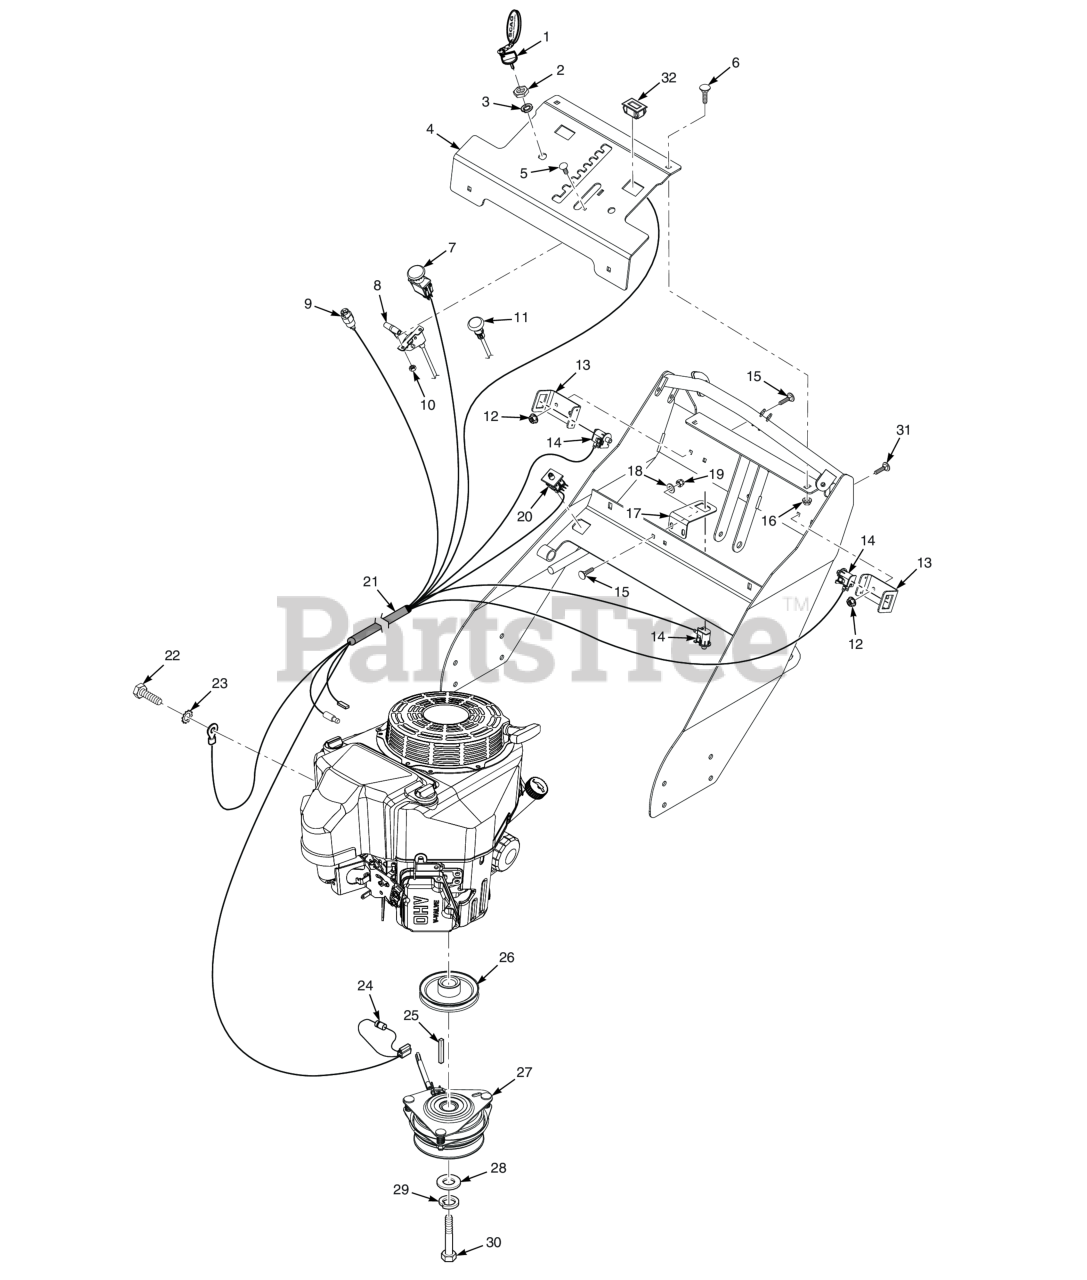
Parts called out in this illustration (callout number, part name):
1	Key, Assembly w/Fob
2	Nut, 5/8-32 Special
3	LOCK WASHER, 5/8" INTERNAL TOOTH
4	Instrument Panel w/Decal
5	Bolt, Carriage #10-24 x 1/2"
6	Bolt, 5/16-18 x .75 RHSN Carriage
7	Switch, PTO - 10 Amp
8	Throttle Cable
9	KEY SWITCH, MANUAL SRT.(INCL. HWD)
10	Nut, Elastic Stop #10-24
11	Choke Control
12	NUT, 1/4-20 SERRATED FLANGE HEX HEAD
13	Bracket, Operator Presence Switch
14	SWITCH, NEUTRAL INTERLOCK
15	Serr. Fl. Hex Head CPSCR, 1/4-20 x 3/4"
16	Nut, Serrated Flange 5/16-18 (Right Front Engine Mounting, Briggs and Kohler Only)
17	Bracket, Neutral Switch (Manual Start)
18	Flatwasher, 5/16-.375 x .875 x .083 (35BV & 37BV-EFI)
19	HEX, NUT, ELASTIC STOP LOCK, 1/4-20
20	Switch, Double Pole - Plunger
21	Wire Harness
22	Bolt, Hex Hd. M8-1.25 x 14mm
23	Lockwasher, 5/16" Ext. Tooth (Kohler x1)
24	Diode, 600V 6 Amp
25	KEY, 1/4 X 1/4 X 2-1/2"
26	Pulley, 4-1/2" Dia. - 1" Bore
27	Electric Clutch Assembly
28	Flatwasher, 7/16-.469 x 1.75 x .25 (48, 52)
29	Lockwasher, 7/16� Spring
30	Bolt, Hex Head 7/16-20 x 3" w/t Patch
31	Bolt, Carriage, 1/4-20 x 1-1/4"
32	Hour Meter, Inductive
